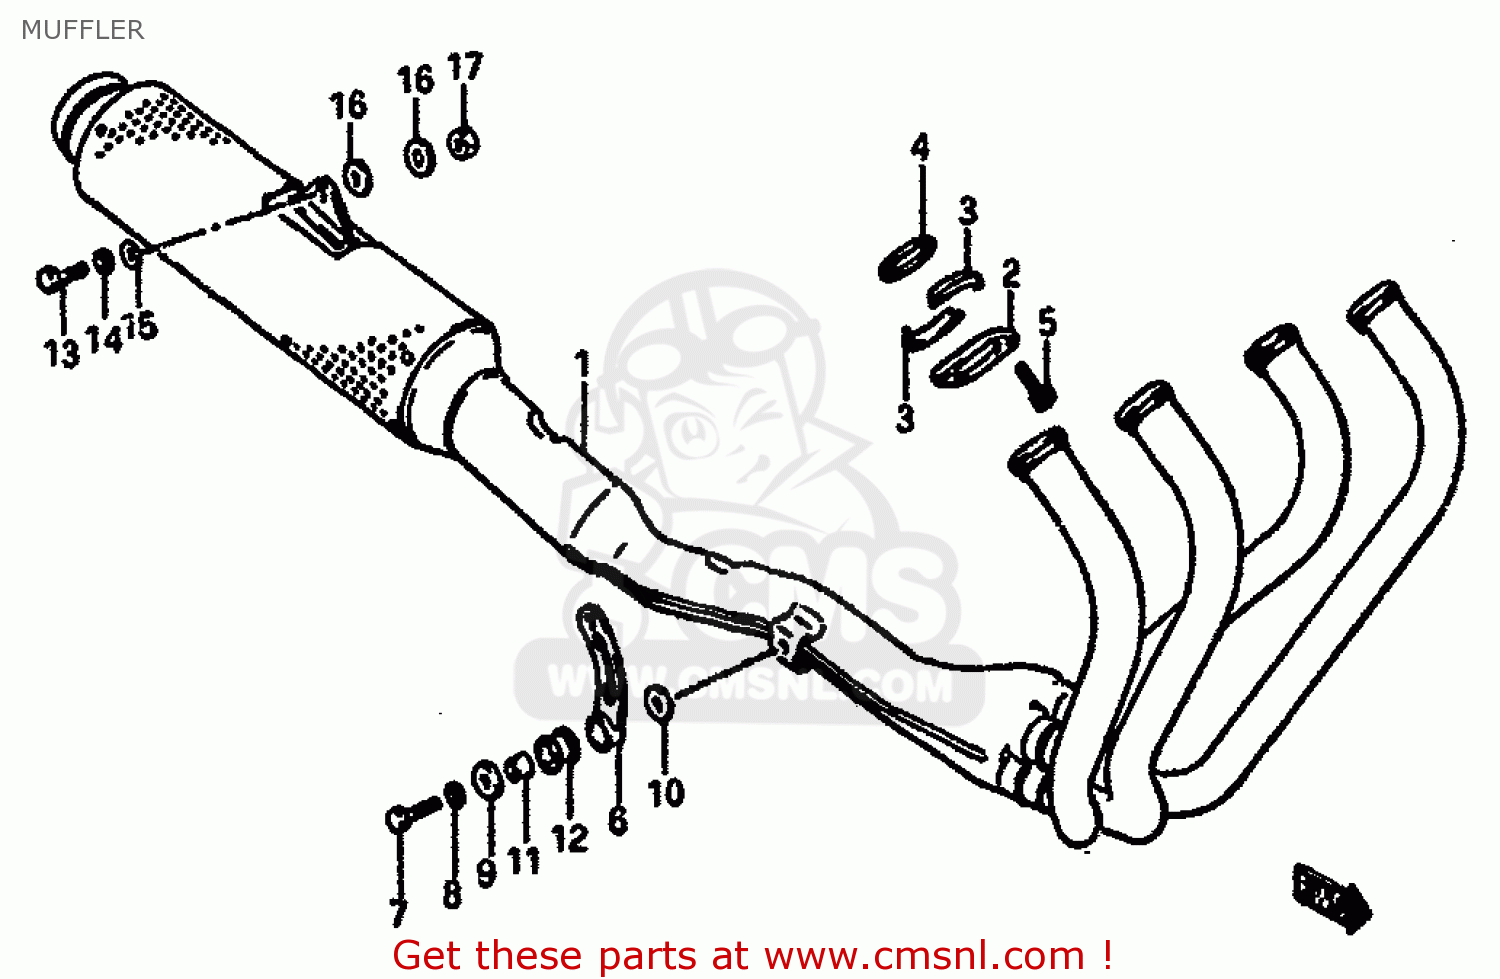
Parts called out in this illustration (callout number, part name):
1	MUFFLER ASSY
2	CLAMP,EXHAUST PIPE
3	PLATE,EXHAUST PIPE
4	GASKET,EXHAUST PIPE (NAS)
5	BOLT
6	DAMPER,MUFFLER SUPPORT
7	BOLT 8X35
8	WASHER
9	WASHER
10	WASHER (8.5X20X1.6)
11	SPACER (8.6X12X17.5)
12	CUSHION
13	BOLT
14	WASHER,LOCK
15	WASHER 10MM
16	WASHER
17	NUT
